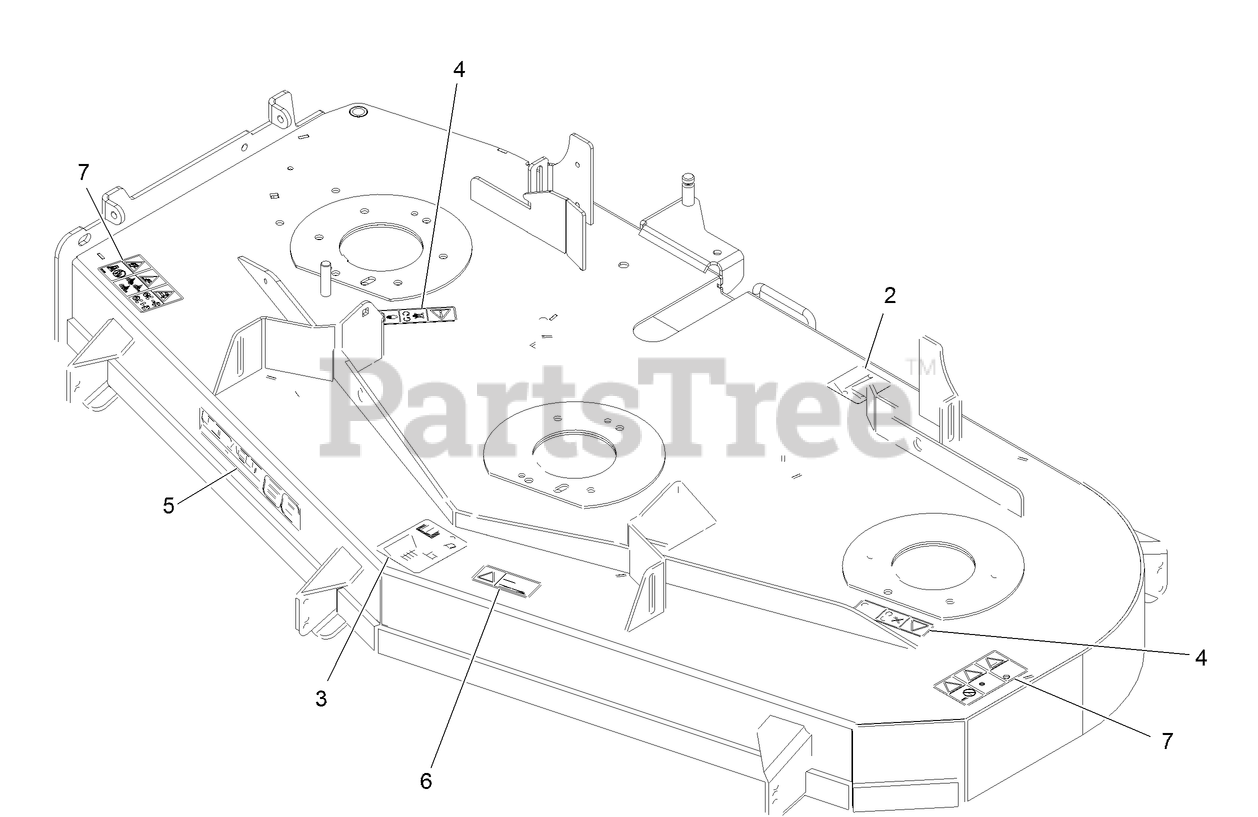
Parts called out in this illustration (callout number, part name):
2	DECAL-ROUTING, BELT
3	DECAL-ROLLER, ANTI-SCALP
4	DECAL-COVER, MISSING
5	DECAL-ULTRACUT 60 SERIES 3
6	DECAL-TORQUE, BOLT
7	DECAL-DANGER THROWN OBJECTS
